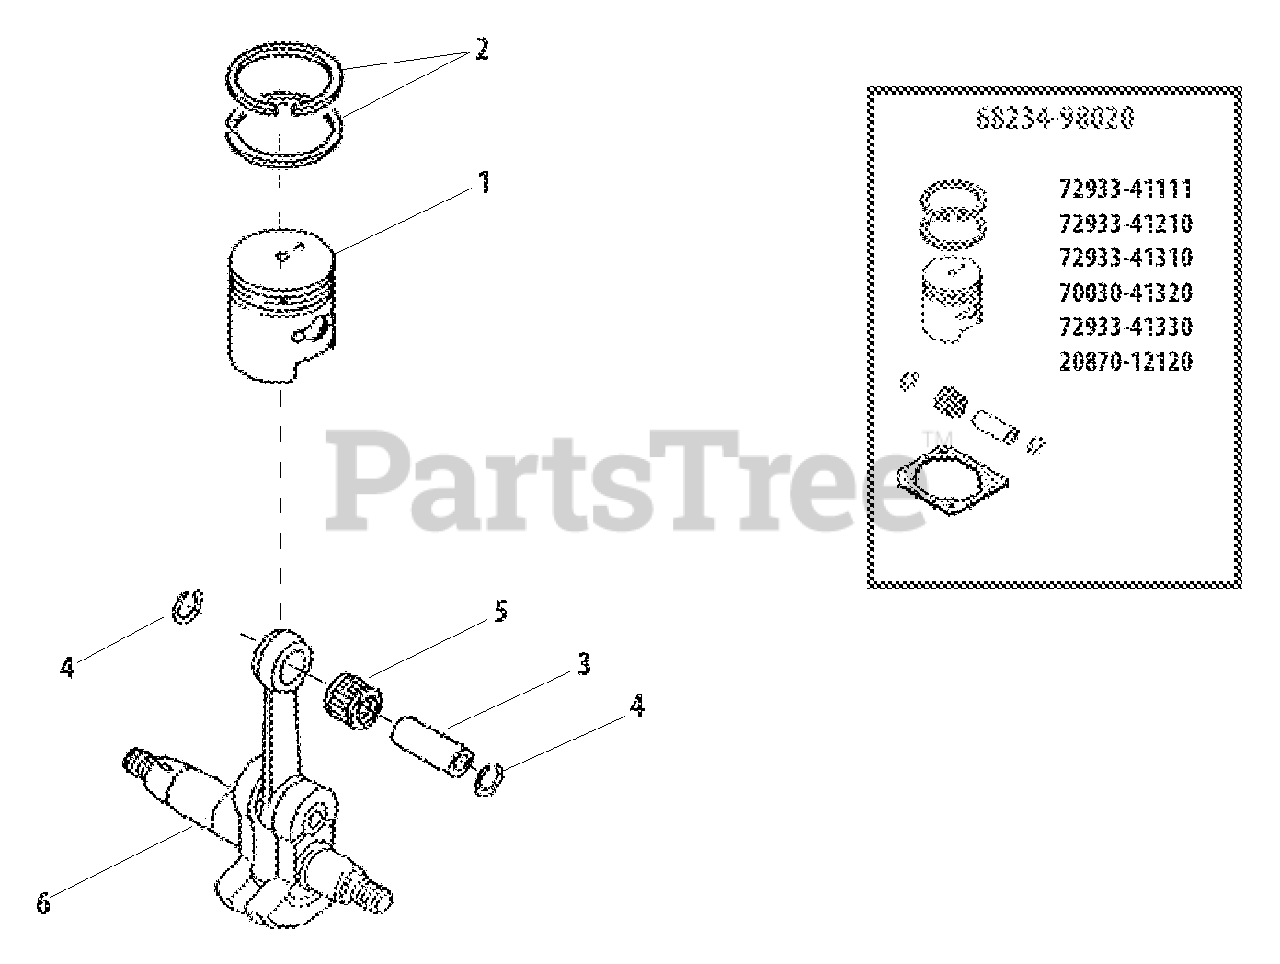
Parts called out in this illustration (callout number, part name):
1	PISTON
2	RING, PISTON
3	PIN, PISTON 8
4	RING, SNAP
5	BEARING, NEEDLE 8
6	CRANKSHAFT ASSY
68234-98020	PISTON KIT
